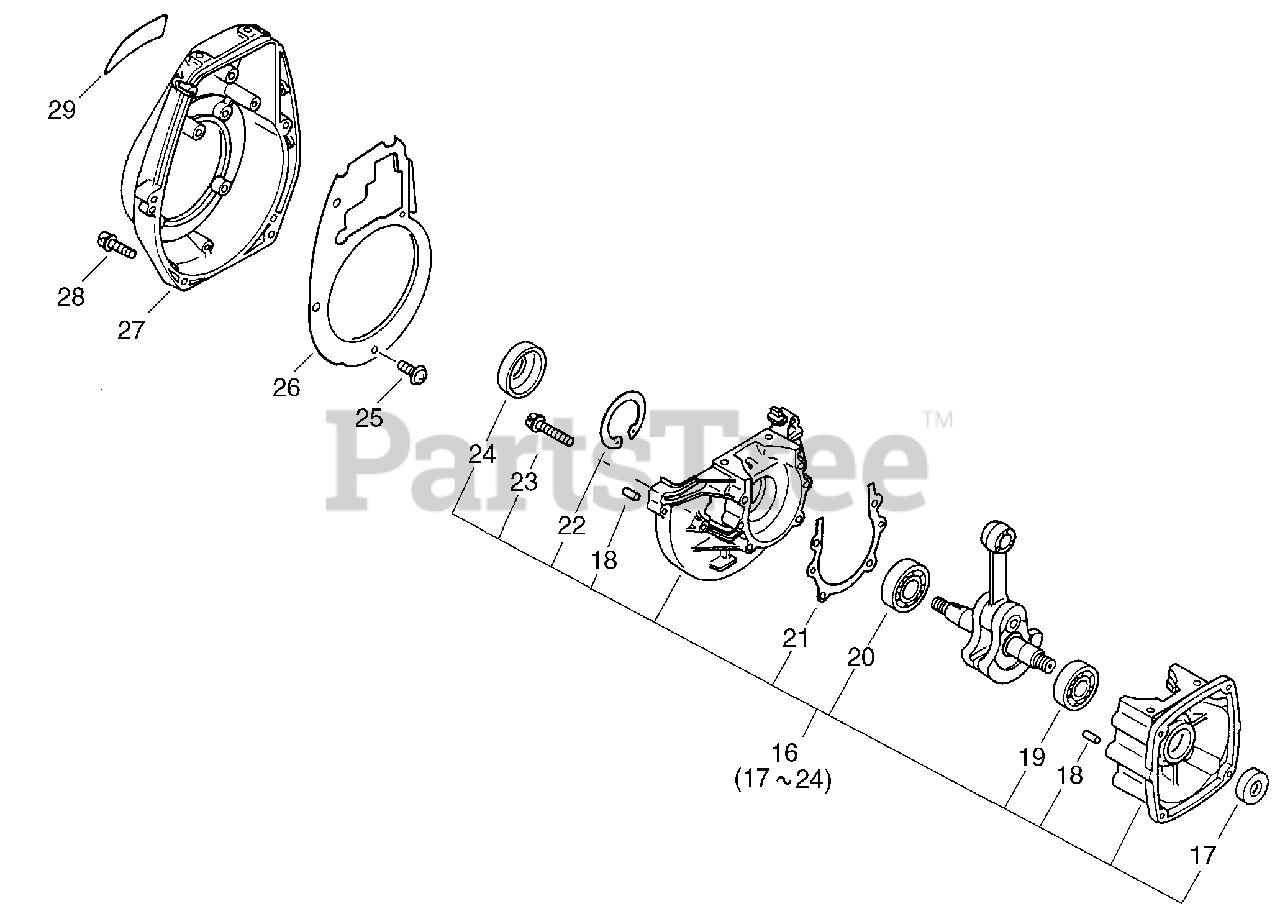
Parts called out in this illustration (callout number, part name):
16	CRANKCASE KIT
17	SEAL, OIL - 12
18	PIN - LOCATING
19	BEARING, BALL - 6201
20	BEARING, BALL - 6202
21	GASKET, CRANKCASE
22	RING, RETAINING - 35
23	SCREW - 5X30
24	SEAL, OIL
25	SCREW - 4X10
26	SHIELD, FAN
27	COVER, FAN - ORANGE
28	SCREW - 5X25
29	LABEL - MODEL SRM-4605
